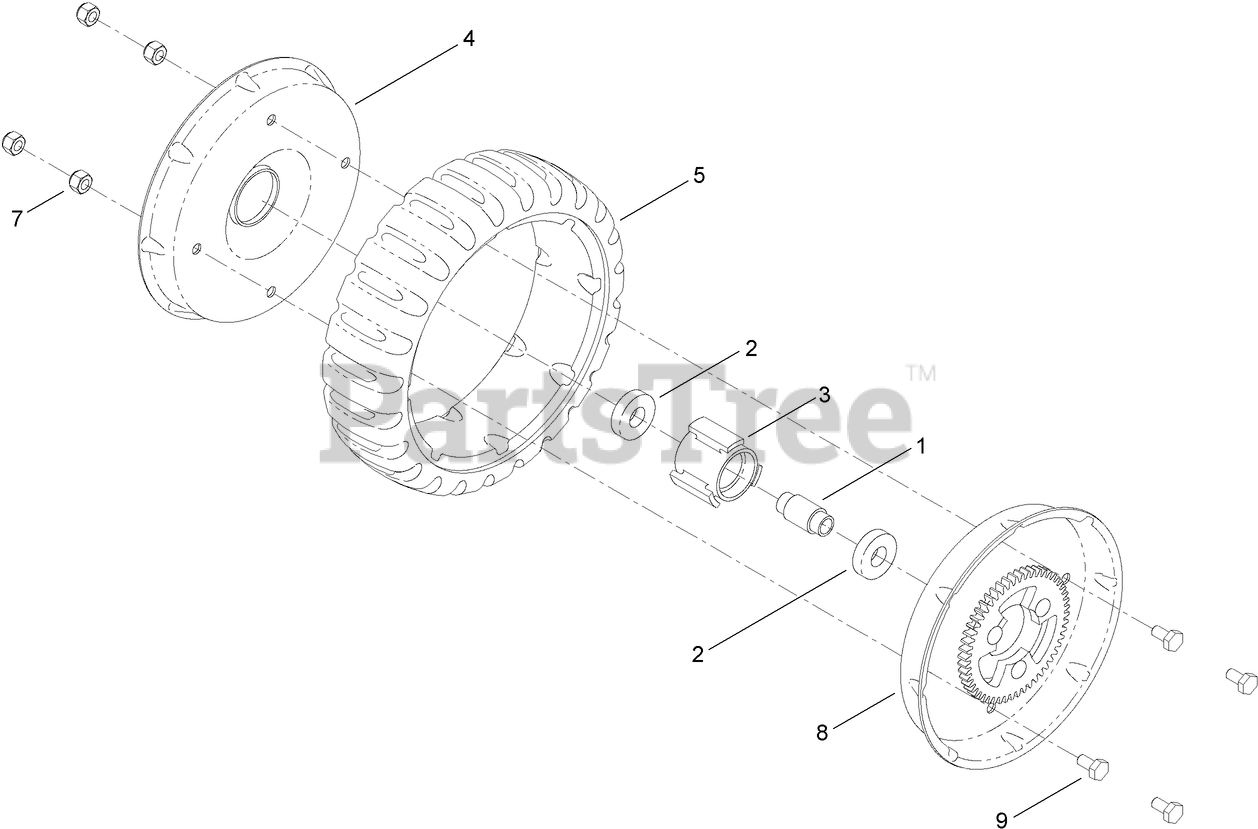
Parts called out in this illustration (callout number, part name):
1	SPACER-BEARING
2	BEARING-BALL
3	HUB-BEARING
4	WHEEL-HALF
5	TIRE-8 INCH
7	NUT-LOCK, NI
8	HUB GEAR ASM
9	SCREW-HH
